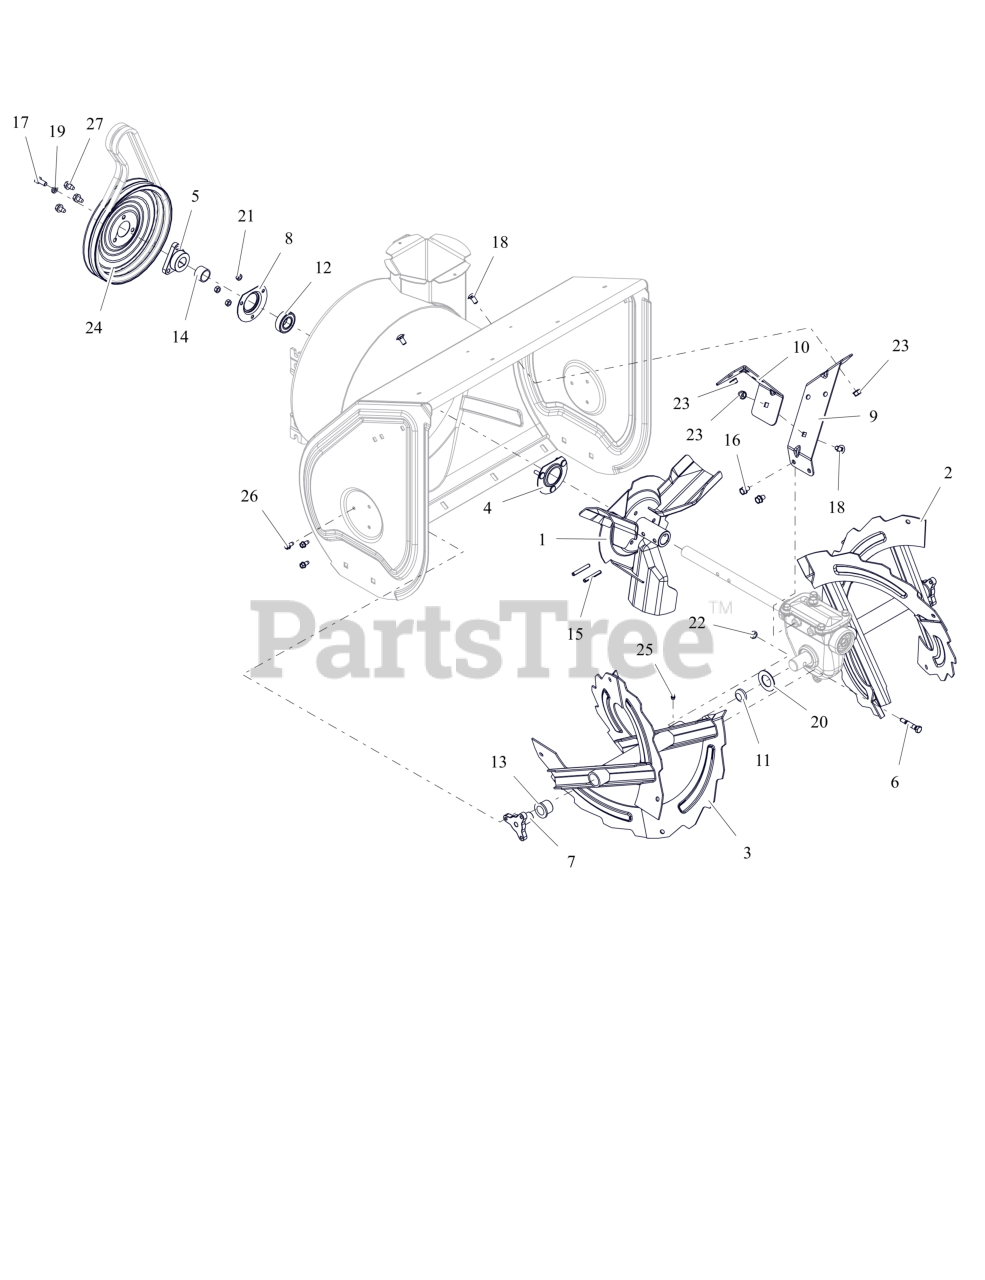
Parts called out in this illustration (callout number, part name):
1	IMPELLER, 3 BLADE-14"
2	RAKE, LH W/ZERK - 24"
3	RAKE, RH W/ZERK - 24"
4	BEARING FLANGE
5	PULLEY HUB, D-BORE .87 PRO
6	SHEAR BOLT SERVICE ASSEMBLY
7	SUPPORT, RAKE BUSHING
8	BEARING FLANGE
9	BRACKET, GEARCASE SUPPORT - LH
10	BRACKET, GEARCASE SUPPORT - RH
11	PLUG, RAKE TUBE
12	BRG-BALL .876 X 1.750 X .50
13	BSHG-FLG, NY.778 ID X 1.018 OD
14	BSHG,SPCR .895X1.065X.693
15	PIN-ROLL .250X1.75
16	BLT, SEMS .31-18X.50 G5 ZCC
17	BLT, HEX .31-24X.750 G5 ZCC
18	BLT,RHSSN.31-18X.625 G5 ZCCP30
19	WSHR, LK-HVY .312X.097 ZCC
20	WSHR- FLT 1.010X1.755X.062 ZCC
21	NUT,LK-CTR .25-20 GA ZCC
22	NUT,LK-CTR .31-18 GA ZCC
23	NUT-LK-TOP-FLG .312-18 GF ZCC
24	PULLEY, SPIN FORM DUAL GROOVE
25	ZERK,FITTING .25X.125 DRIVE IN
26	SCR-TAP .25-20X.50 HWH ZCC
27	SCR,TAP .312-18X.50 HWH TR ZCC
